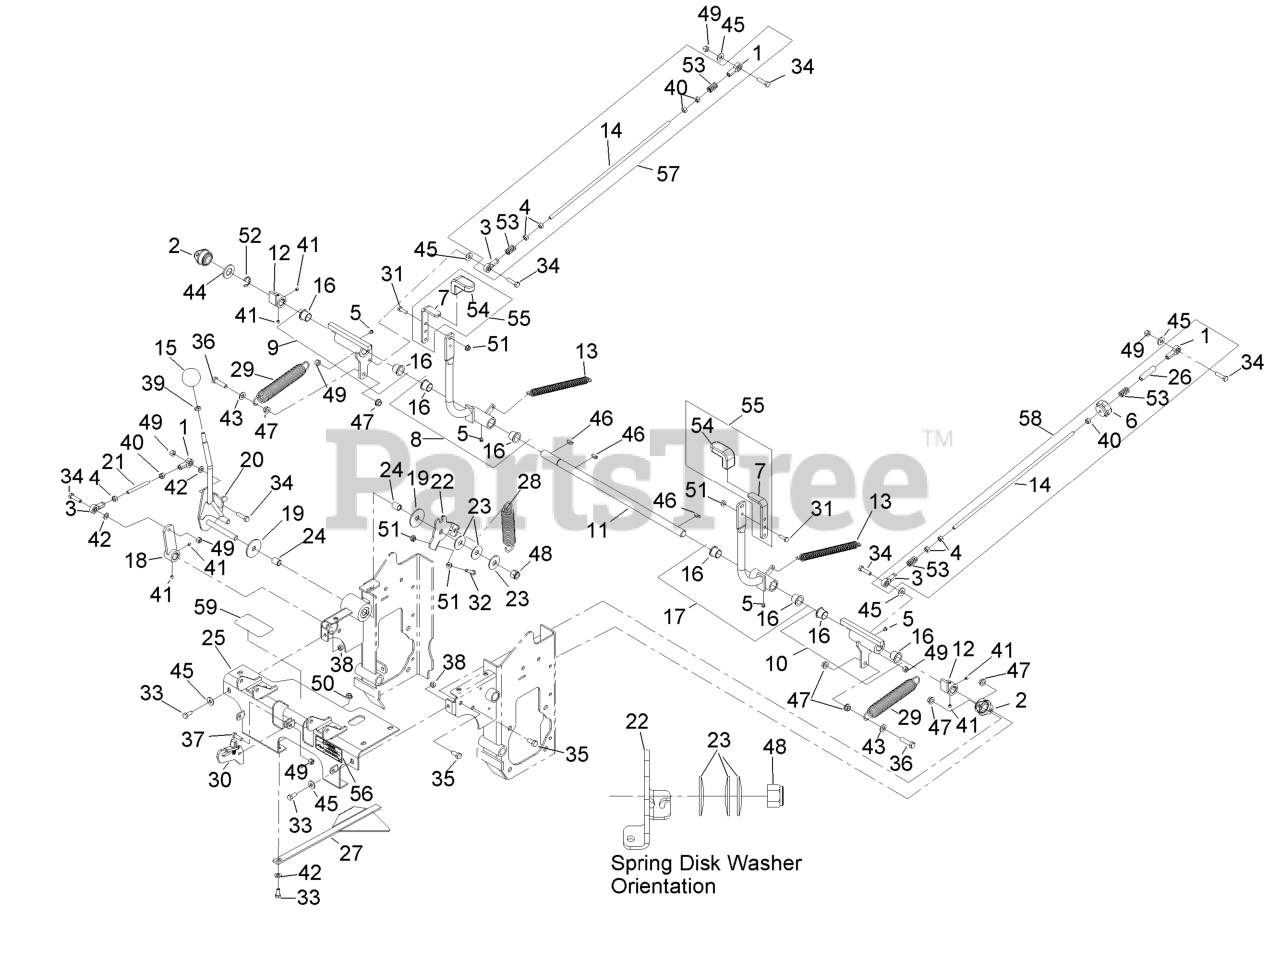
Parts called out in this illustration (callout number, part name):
1	BALLJOINT-RH
2	BEARING-FLANGE, SIDE
3	BALLJOINT-LH
6	KNOB-TRACKING
7	ASM,HANDLE W/GRIP
8	ASM,STEERING LEVER RH W/B
9	ASM,ACTUATOR RH W/BEARING
10	ASM,ACTUATOR LH W/BEARING
11	SHAFT,SPEED CONTROL
12	WLD,HUB SPEED CONTROL
13	SPRING,EXTENSION
14	LINKAGE,ROD LH STEERING (
15	KNOB-BALL, SPEED CONTROL
16	BEARING-FLANGE, IGLIDE
17	ASM,STEERING LEVER LH W/B
18	WLD,CONTROL ARM (PLATED)
19	DISC-FRICTION
20	WLD,SPEED CONTROL LEVER(P
21	ROD,THREADED CONTROL LINK
22	PLATE,SPEED CONTROL FRICT
23	WASHER-DISC, SPRING
24	BEARING,PLASTIC 1/2"
25	Asm, Console W/Decals
27	GUIDE-PLENUM
28	SPRING,EXTENSION (PLATED)
29	SPRING-EXTENSION
31	SCREW-HH
32	SCREW-HH
33	SCREW-HH
34	SCREW-HH
35	SCREW-HH
36	SCREW-HH
37	SCREW-HH
38	NUT-HEX
39	NUT-JAM
40	NUT-HEX
41	SCREW-SET, HSH
42	WASHER-PLAIN
43	WASHER-FLAT
44	WASHER-FLAT
45	WASHER-FLAT
46	KEY-WOODRUFF
47	NUT-HHF, WHIZ
48	NUT-HEX
49	NUT-LOCK, NI
53	SPRING-COMPRESSION
54	GRIP-HANDLE, STEERING
55	ASM,HANDLE W/GRIP
56	DECAL-DRIVELINE
57	ASM,RH PUMP LINKAGE
58	ASM,LH PUMP LINKAGE
59	DECAL,WHEEL MOTOR RELEASE
